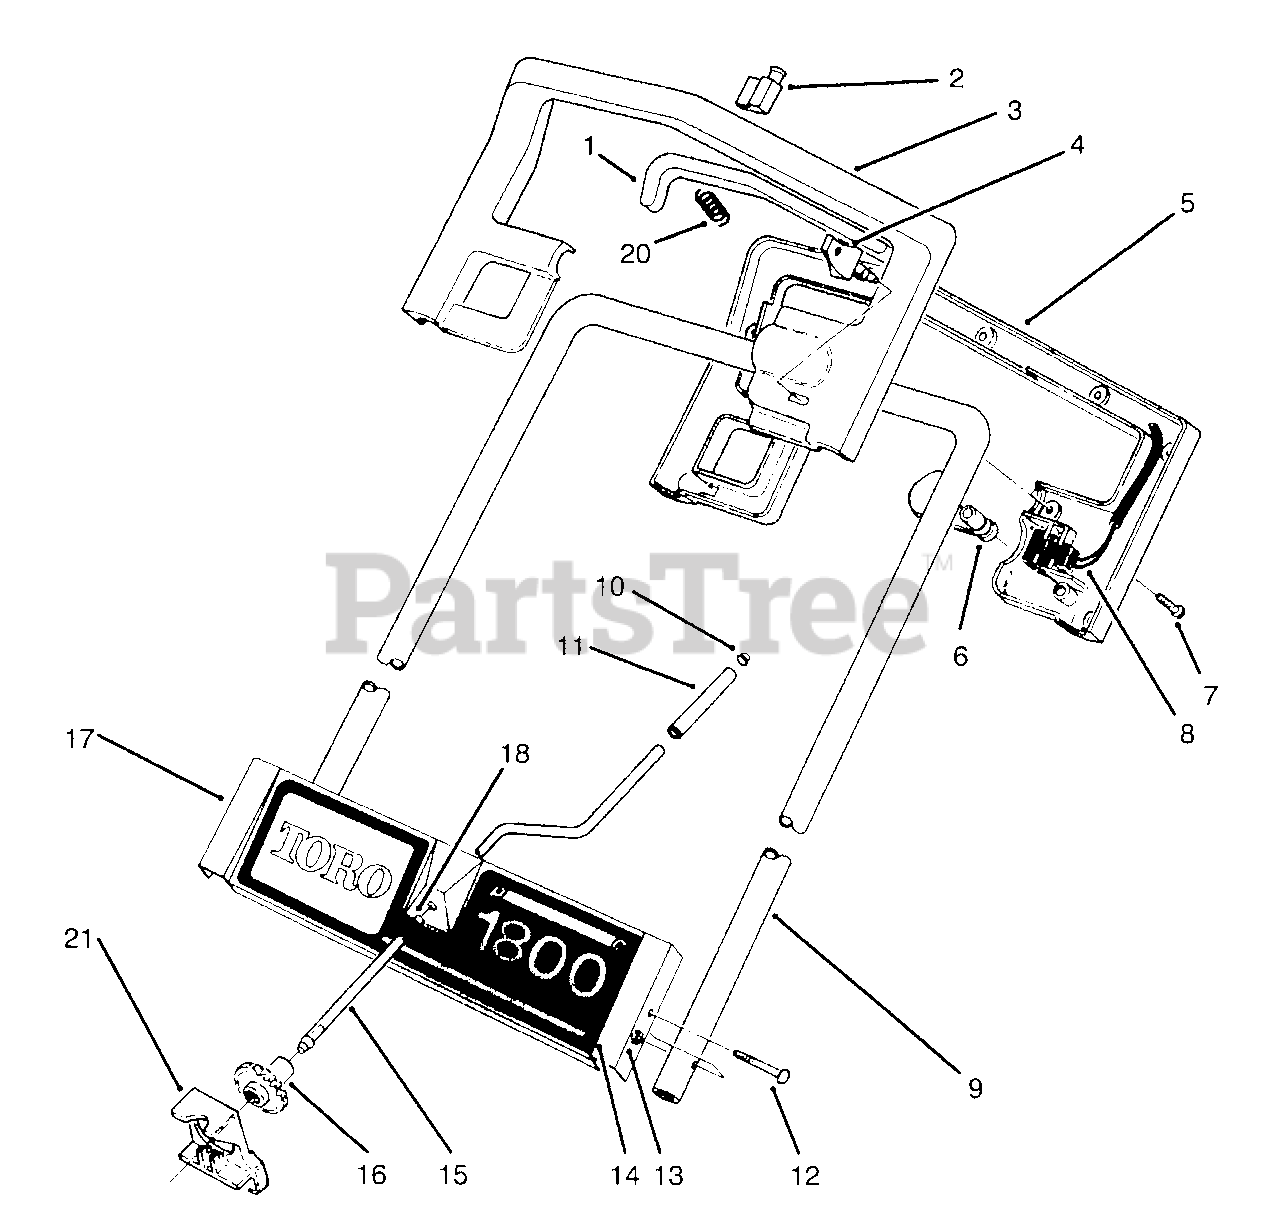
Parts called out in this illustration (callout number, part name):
1	Bar-Switch
2	Switch
3	Handle-Upper Control
5	Handle-Lower Control
6	Tab-Lock
7	Screw-Pan Hd. Form.
8	Cord-Supply
9	Tube-Upper Handle
10	Nut-Push
11	Sleeve-Chute Crank
12	Screw-Hex Hd. Mach.
13	Nut-Lock
14	Decal-Escutcheon
15	Rod-Chute Crank
16	Gear-Chute Crank
17	Plate-Escutcheon
18	Bushing-Snap In
21	Brake-Gear
